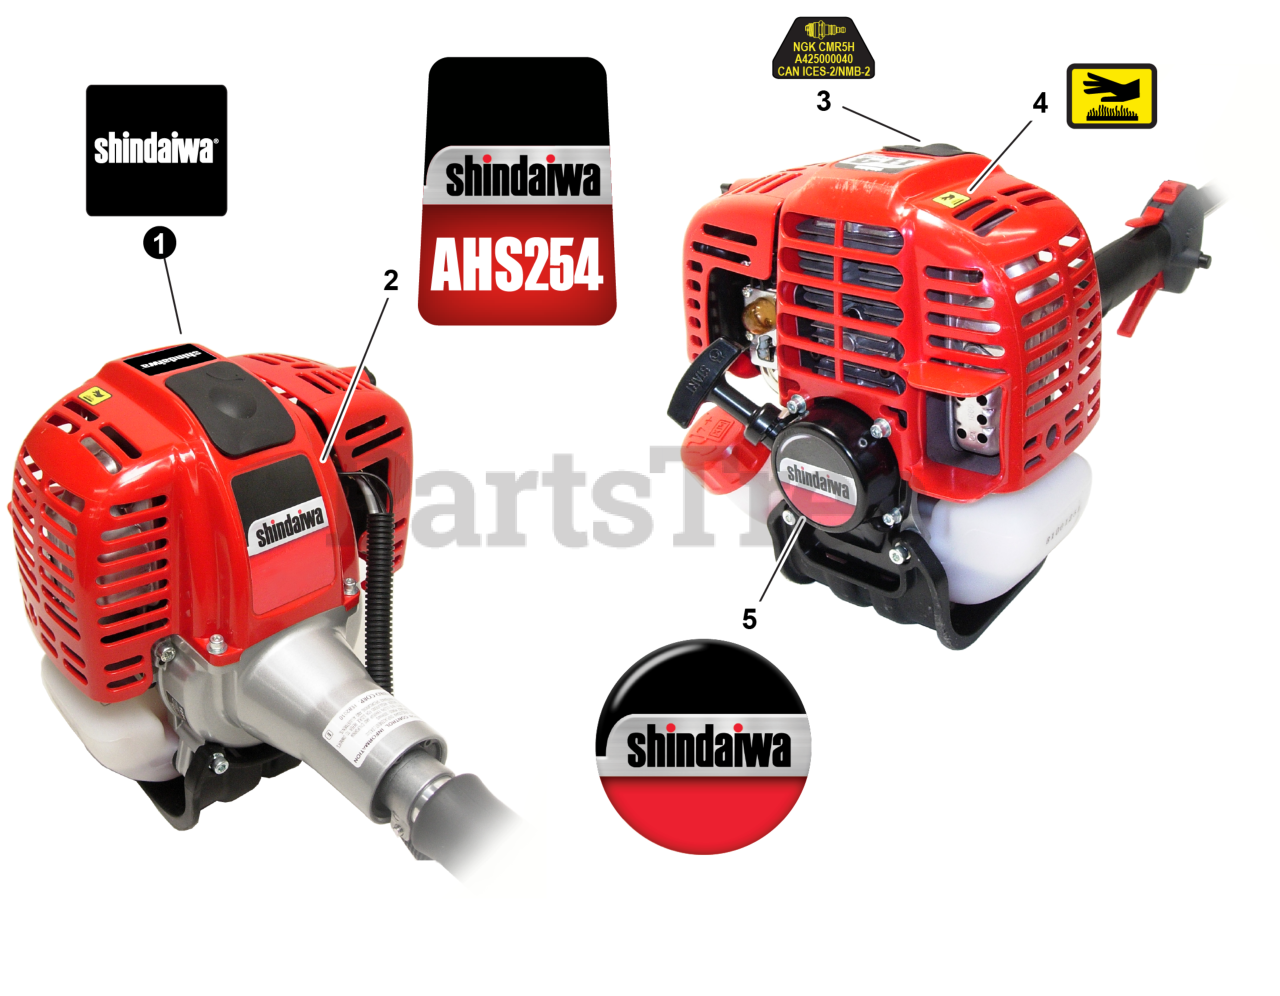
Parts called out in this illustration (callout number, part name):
1	LABEL - SHINDAIWA
2	LABEL - AHS254
3	LABEL - SPARK PLUG - CMR5H
3	LABEL - CAUTION - HOT
4	LABEL - RECOIL STARTER
